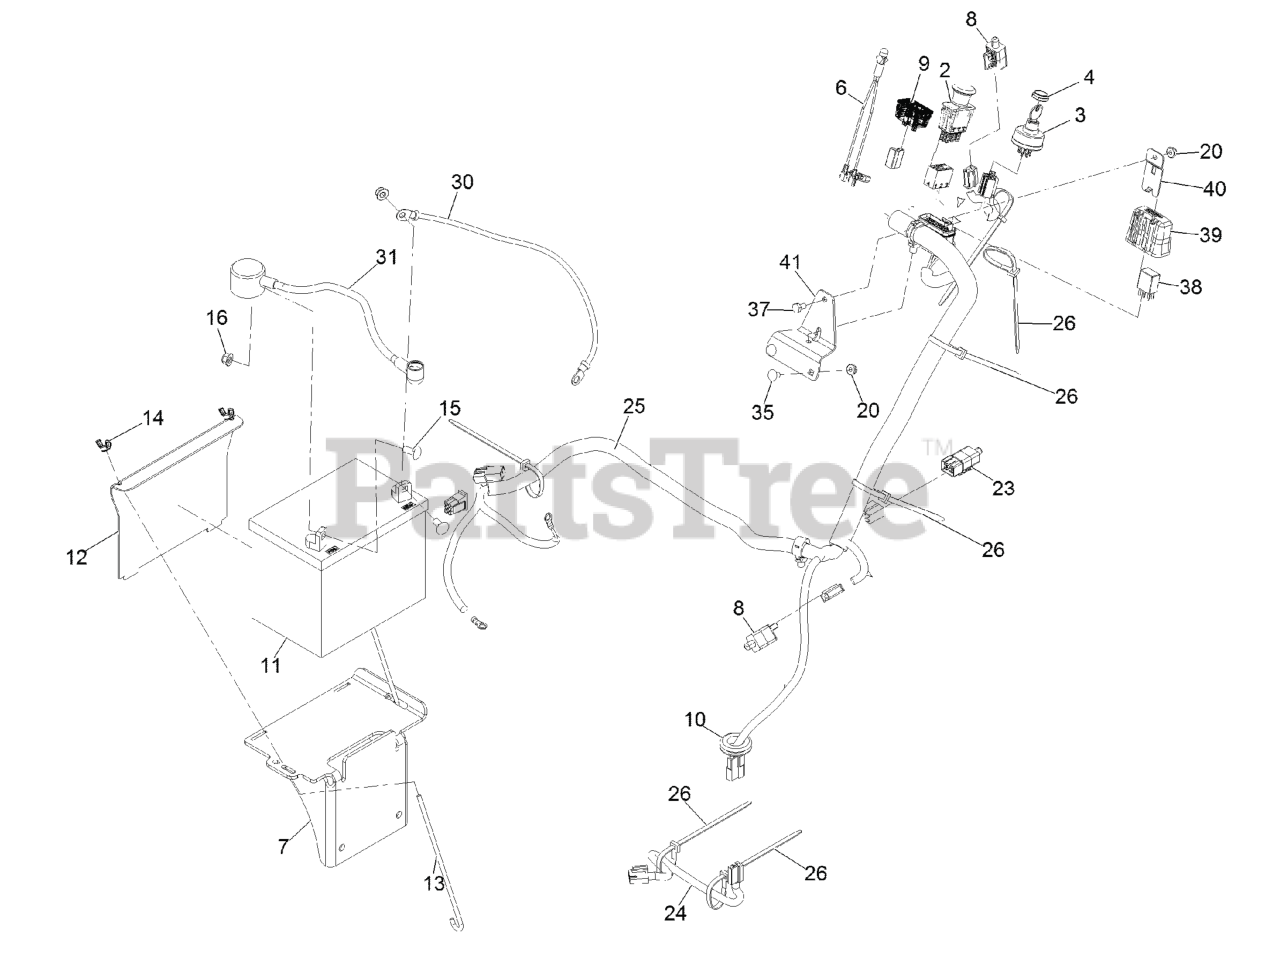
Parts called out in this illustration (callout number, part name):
2	SWITCH-PTO
3:1	WASHER-LOCK
4	NUT-SWITCH, IGNITION
6	INDICATOR-LED, RED
7	WELD, BATTERY MOUNT
9	METER-HOUR
10	GROMMET
12	BRACKET, BATTERY HOLD DOW
13	BOLT-HOLDDOWN
14	WINGNUT
15	BOLT-CARR
16	NUT-HF, NI
23	SWITCH, 2 POLE
24	HARNESS-CLUTCH PIGTAIL
25	HARNESS-MAIN
26	TIE-PLASTIC
31	ASM,POSITIVE BATTERY CABL
32	NUT-LOCK, NI
34	TIE-PLASTIC
